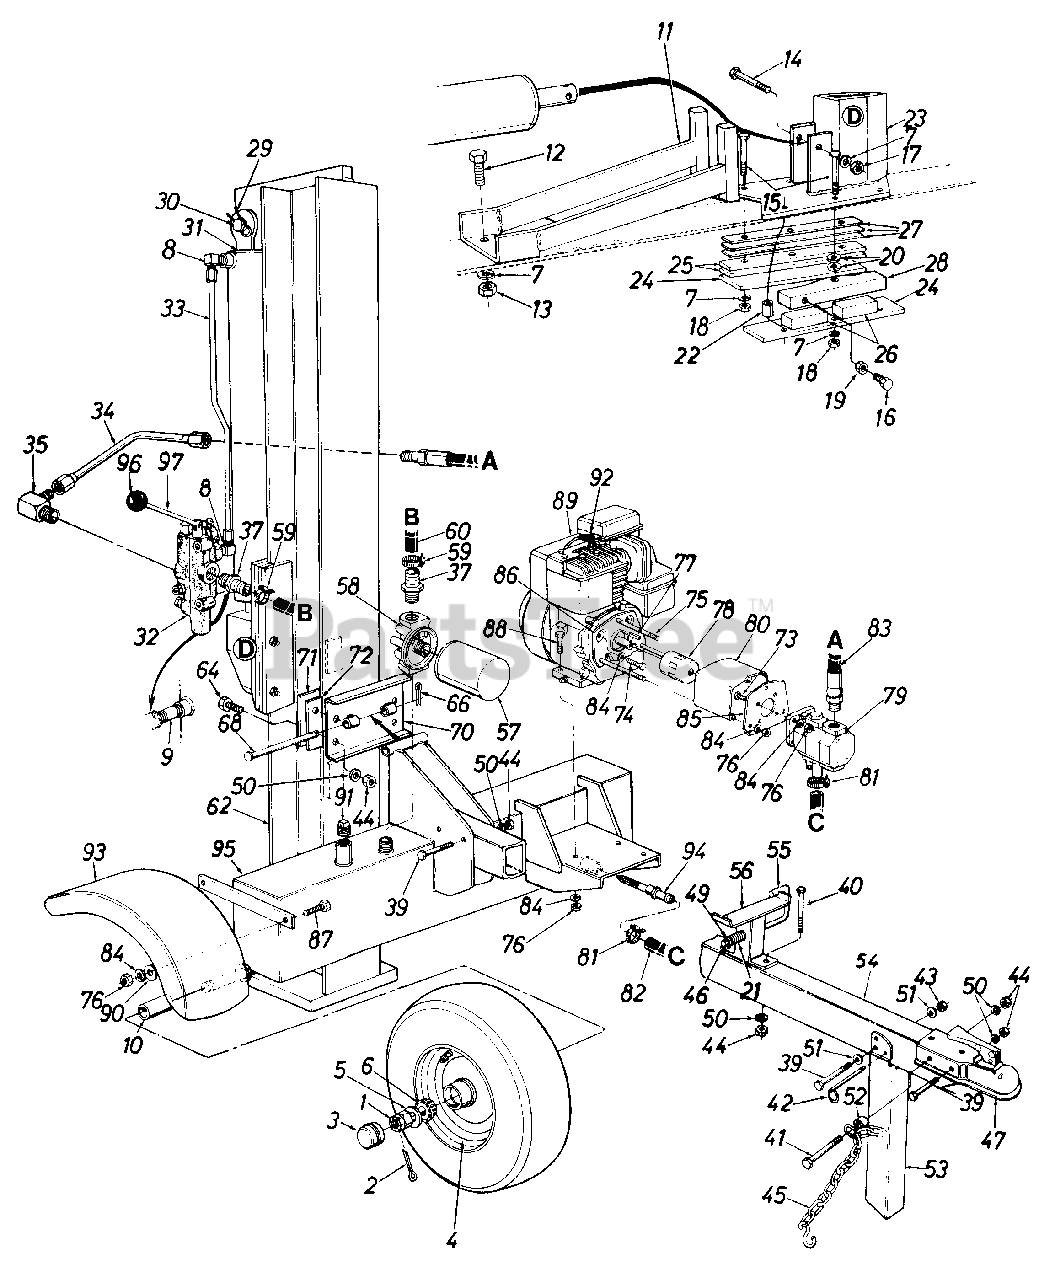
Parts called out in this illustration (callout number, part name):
1	Hex Castle Nut 3/4-16 Thd.
2	Cotter pin 5/32" Dia.
3	Hub Cap
5	Fl-Wash. .76" I.D. x 1.5" O.D.
6	Roller Bearing
7	L-Wash. 1/2" I.D.
8	90ø Solid Male Adaptor
9	Pipe Nipple '/2 NPT
10	Spacer 1.56" Lg.
11	Stripper Ass'y.
12	Hex Bolt 1/2-13 x 2" Lg. (Grade 8)
13	Hex Nut 1/2-13 Thd. (Grade 5)
14	Hex Bolt 1/2-20 x 3" Lg. (Grade 8)
15	Hex Bolt 1/2-20 x 2.75" Lg. (Grade 8)
16	Hex Bolt 3/8-24 x 1.5" Lg.
17	Hex L-Nut 1/2-20 Thd.
18	Hex Nut 1/2-20 Thd.
19	Hex Jam Nut 3/8-24 Thd. (Grade 5)
20	Fl-Wash. 53" I.D. x .94" O.D.
21	Comp. Spring 4" Lg.
22	Spacer 1/2" I.D. x .86" Lg.
23	Wedge Ass'y.
24	Pusher Back Plate
25	Fixed Side Gib
27	Adjustable Gib Shim
29	External Cotter Pin
30	Cylinder Mounting Pin
33	Metal Pressure Tube
34	Pressure Tube
35	90ø Solid Male Adaptor
37	3/4" Hose Barb.
39	Hex Bolt 3/8-16 x 3" Lg. (Grade 8)
40	Hex Bolt 3/8-16 x 5" Lg.
41	Hex Bolt 3/8-16 x 3.25" Lg. (Grade 8)
42	Quick Release Pin
43	Hex L-Nut 3/8-16 Thd.
44	Hex Nut 3/8-16 Thd.
45	Chain-Tow Hitch
46	Spring Roll Pin 1/8" Dia.
47	Hitch Coupler
49	Fl-Wash. .635" I.D. x .93" O.D.
50	L-Wash. 3/8" I.D.
51	Fl-Wash. .406" I.D. x .75" O.D.
52	Spacer.27" Lg.
53	Jack Stand Ass'y.
54	Tongue Tube
55	Locking Rod
56	Beam Support Ass'y.
57	Filter Element
58	Filter Head
59	Adj. Hose Clamp
60	Return Hose 3/4" I.D. x 30" Lg.
62	Vertical Beam Ass'y.
64	Hex Bolt 3/8-16 x 1.5" Lg. (Grade 5)
66	Cotter Pin 1/8" Dia.
68	Hinge Pin
70	Beam Hinge
71	Beam Hinge Back Plate
72	Beam Hinge Spacer
73	Hex Bolt 5/16-24 x 1" Lg.
74	Hex Bolt 5/16-24 x .62" Lg.
75	Hex Bolt 5/16-24 x 4" Lg.
76	Hex Nut 5/16-24 Thd.
77	Sq.-Key 3/16" x .75"
78	Flexible Coupling
79	Two Volume Pump
80	Coupling Shield
81	Hose Clamp 518"
82	Suction Hose 1" I.D.
83	High Pressure Hydraulic Hose 56"
84	L-Wash. 5/16" I.D.
87	Hex Bolt 5/16-24 x 75n Lg.
88	Hex Bolt 5/16-24 x 1.75" Lg.
89	Engine
90	Fl-Wash. .344" I.D. x .875" O.D.
91	L-Vent Pipe Plug
92	Spark Plug Boot
93	Fender
94	Strainer Ass'y.
95	Tank Ass'y.
96	Ball Knob
97	Control Handle
